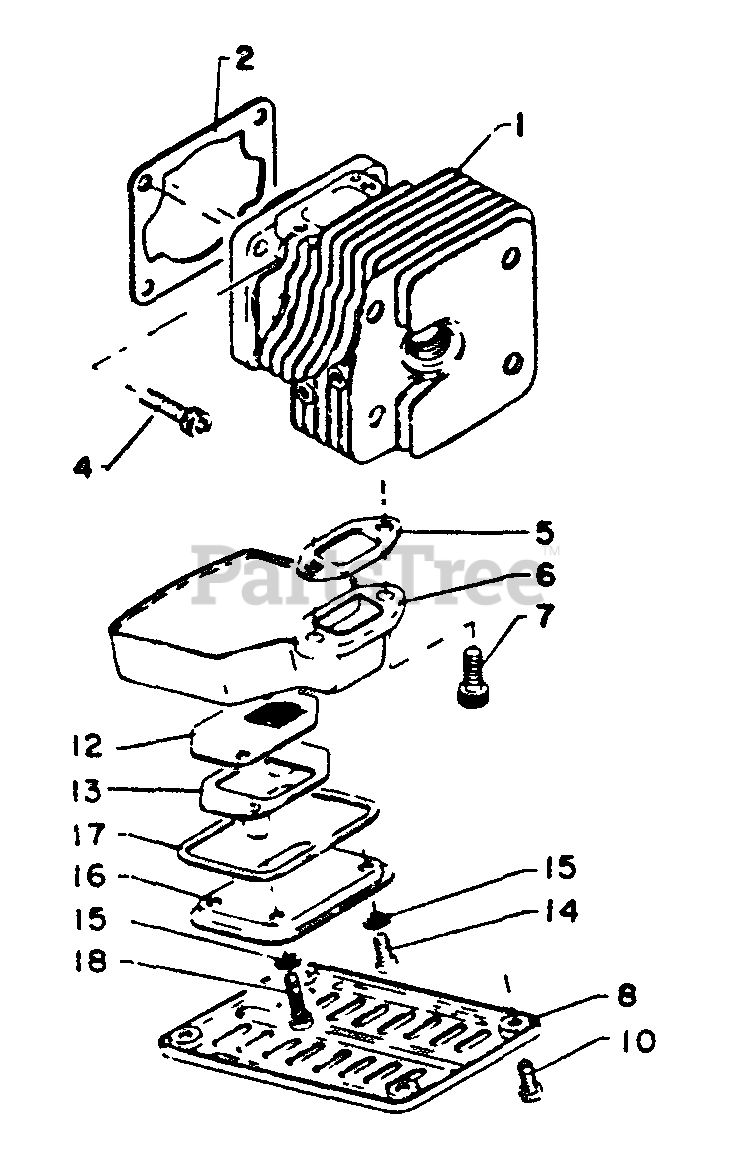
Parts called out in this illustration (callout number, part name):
1	CYLINDER
2	GASKET, CYLINDER
4	SCREW - 5X20
5	GASKET, EXHAUST
6	COVER, MUFFLER
7	SCREW - 5X15
8	COVER, MUFFLER
10	SCREW - 4X10
12	SCREEN, SPARK ARRESTOR
13	RETAINER, SCREEN
14	SCREW - 4X6
15	LOCKWASHER - 4
16	COVER, MUFFLER
17	GASKET, EXHAUST
18	SCREW - 4X14
